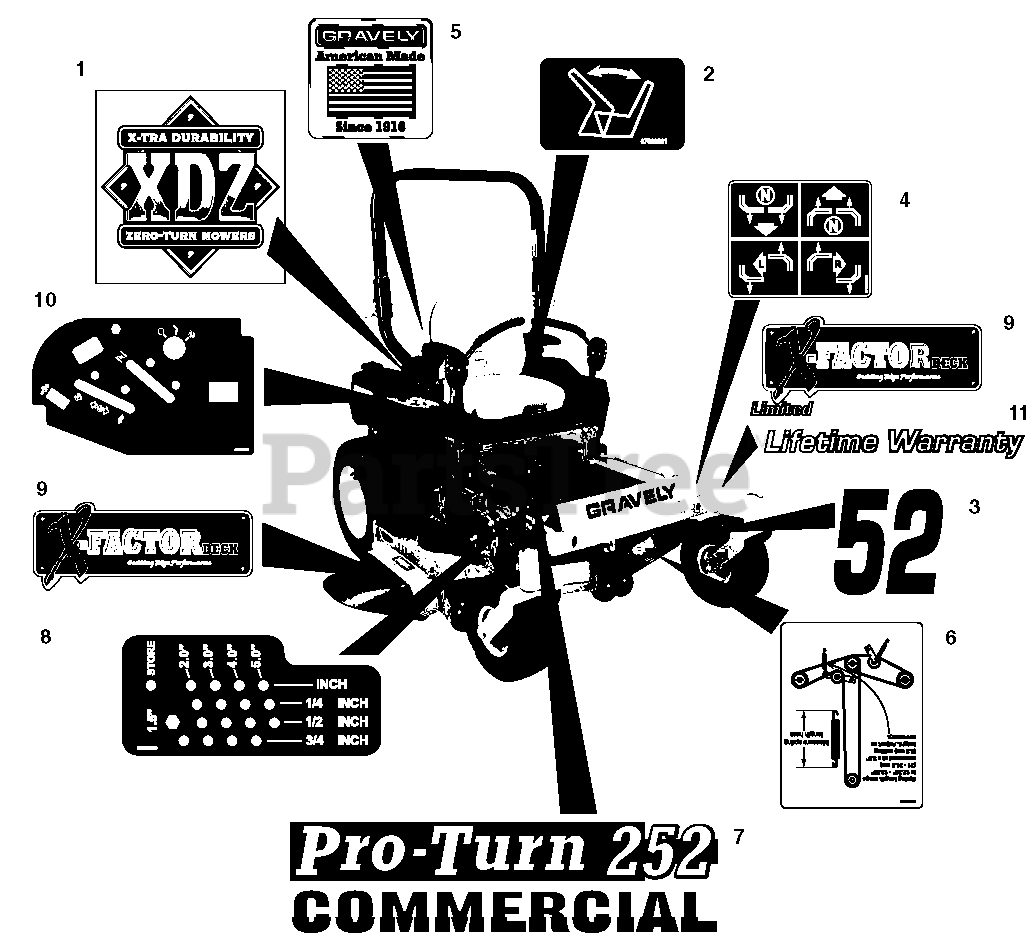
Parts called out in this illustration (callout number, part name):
1	Decal, XDZ
2	Decal, Seat Release
3	Decal, 52 (184)
3	Decal, 60 (185, 187)
3	Decal, 66 (186
4	Decal, Instructional Steering
5	Decal, Gravely American Made
6	Decal, Belt Routing
7	Decal, Pro-Turn 252 (184)
7	Decal, Pro-Turn 260 (185, 187)
7	Decal, Pro-Turn 266 (186)
8	Decal, Height of Cut
9	Decal, X-Factor Deck
10	Decal, Control Panel
11	Decal, Limited Lifetime Warranty
